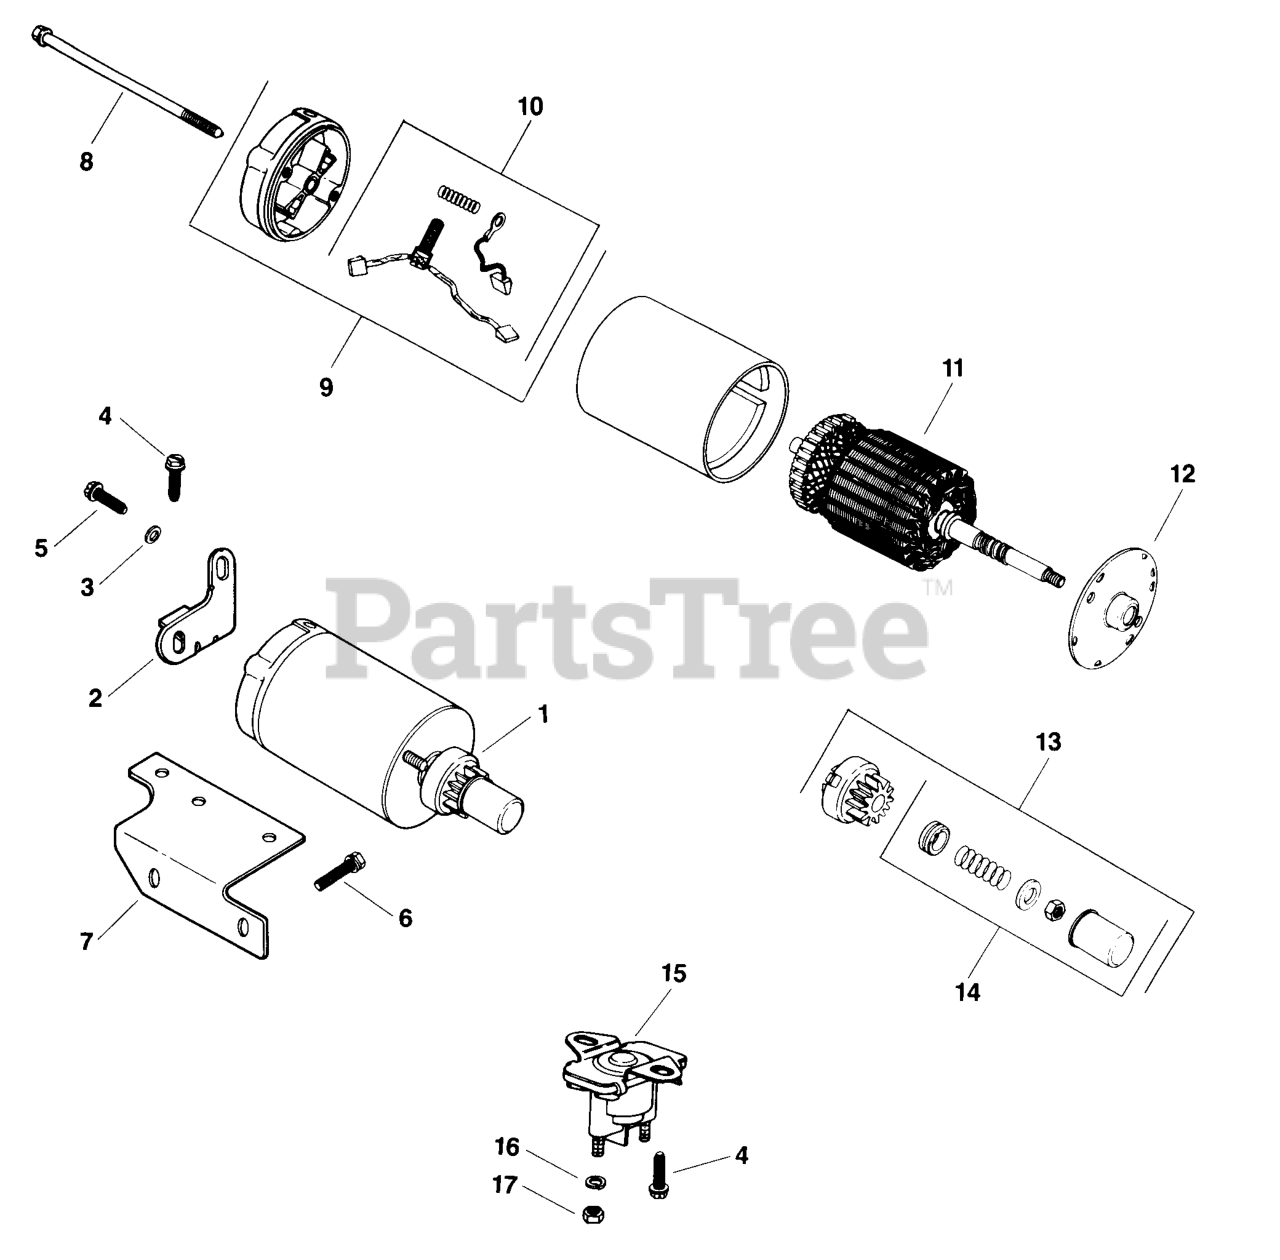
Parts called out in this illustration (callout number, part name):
1	STARTER - USE 41 098 06
2	BRACKET-(#DSC)
3	WASHER, PLAIN 1/4"
5	SCREW, WSH HD TAP 1/4-20X3/4" USE 25 086 100-S
8	BOLT, STARTER 1/4-20X5-1/16"-(#DSC)
9	CAP - USE 52 227 03
10	KIT - USE 82 755 28
11	ARMATURE - DISCONTINUED
12	CAP - USE 41 081 05
15	SOLENOD - USE 25 435 01
